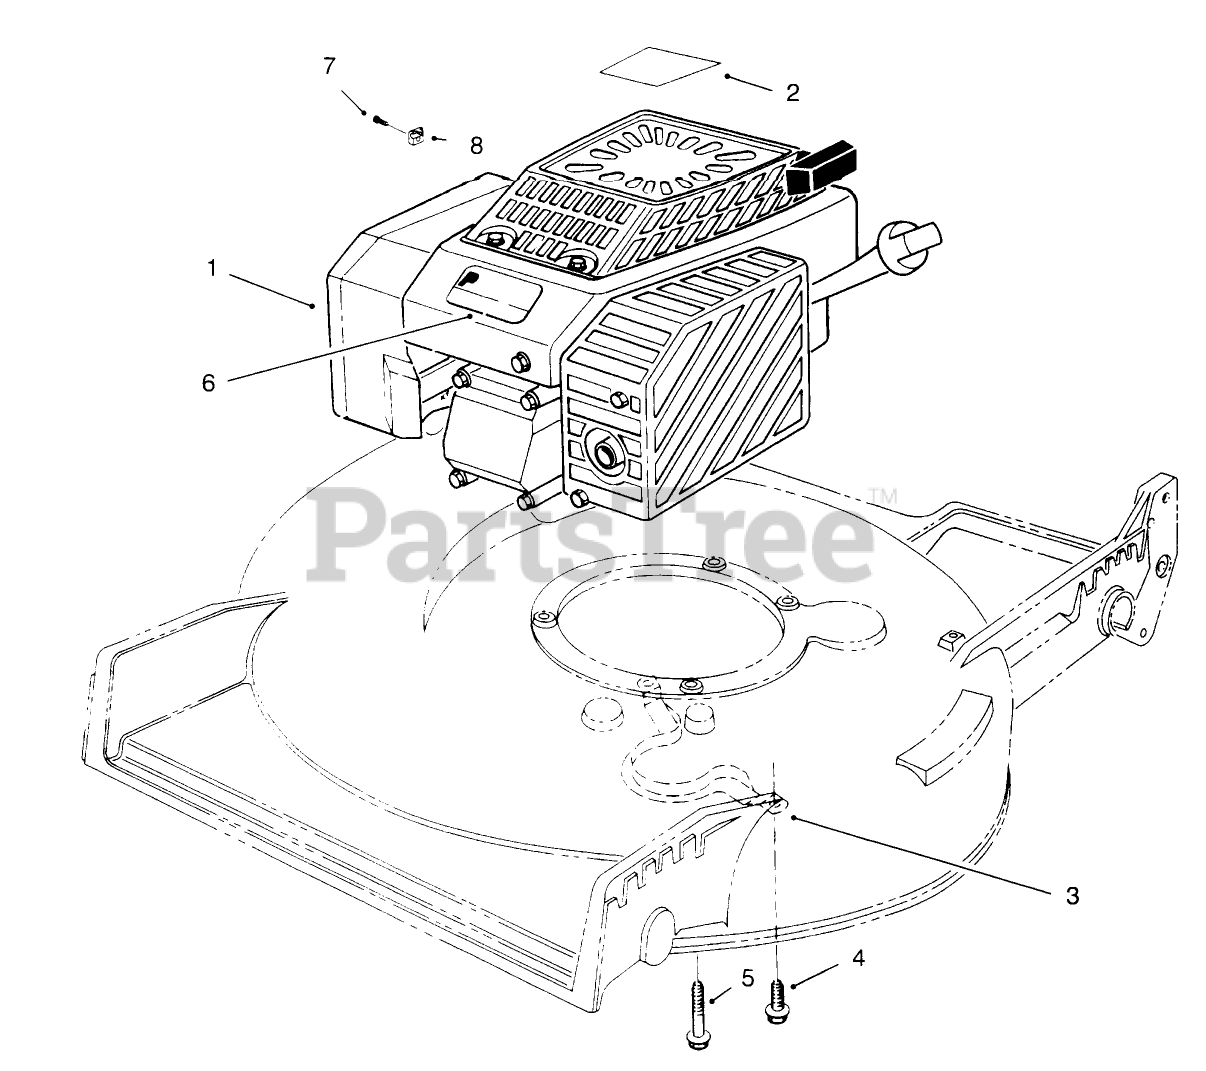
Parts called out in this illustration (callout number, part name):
1	Engine-Complete (Incl. Ref. #2, & 6) (Used on Serial No. 6900001-6901101)
1	Engine-Complete (Incl. Ref. #2, & 6) (Used on Serial No. 6901102 & Up)
2	DECAL - ENGINE
3	Guide-Belt
4	SCREW-HWHTF
5	SCREW-HWH
6	DECAL - PROLINE
7	CLAMP SCREW F/W ENGINE
8	CLAMP-CASING
